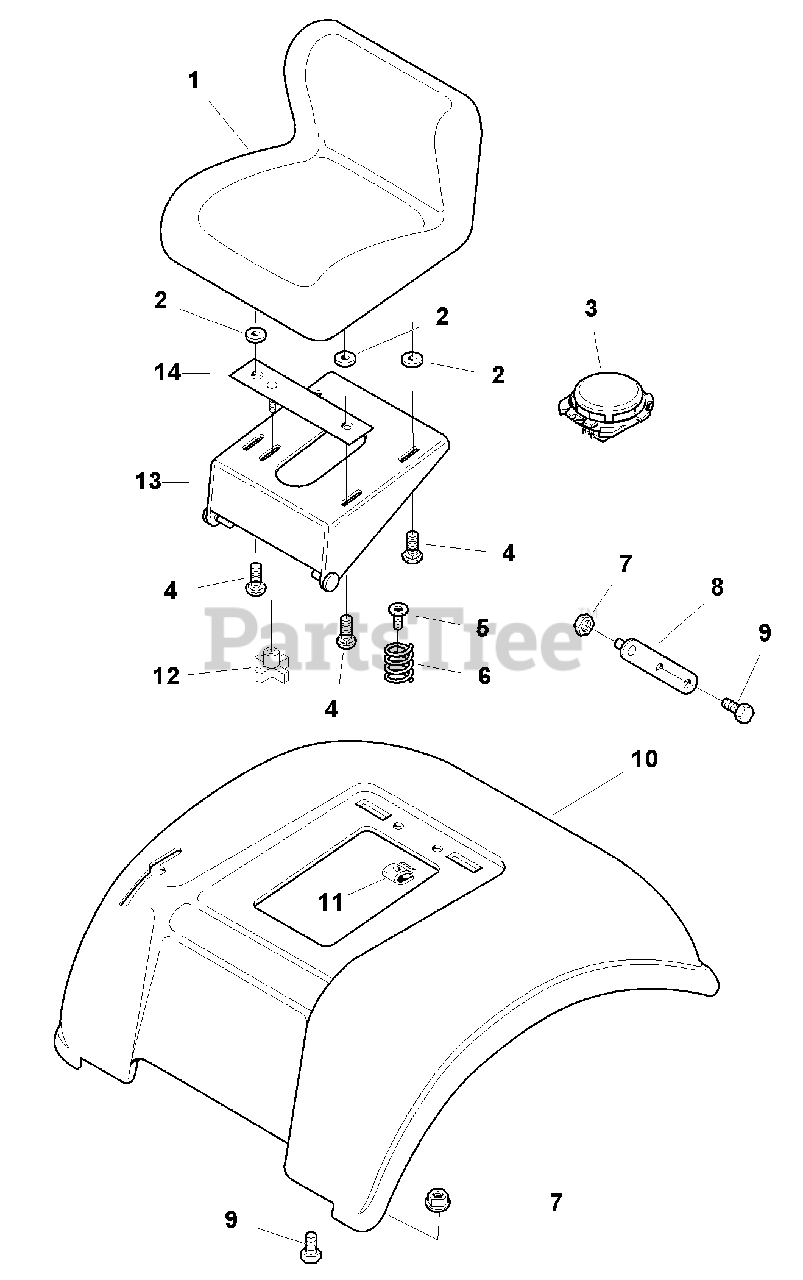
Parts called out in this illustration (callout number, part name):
1	SEAT
2	WASHER
3	SWITCH, Seat
4	CARRIAGE BOLT, 5/16-18 x 3/4
5	SCREW, Flat Head, 5/16-18 x 1-1/4
6	SPRING, Compression
7	NUT, Hex Head Whiz Lock, 5/16-18
9	CAPSCREW, Hex Head, 5/16-18 x 3/4
10	DECK, Seat, Orange
11	NUT, Speed 5/16-18
13	SUPPORT & PIN ASSEMBLY
14	CLAMP & SCREW ASSEMBLY
